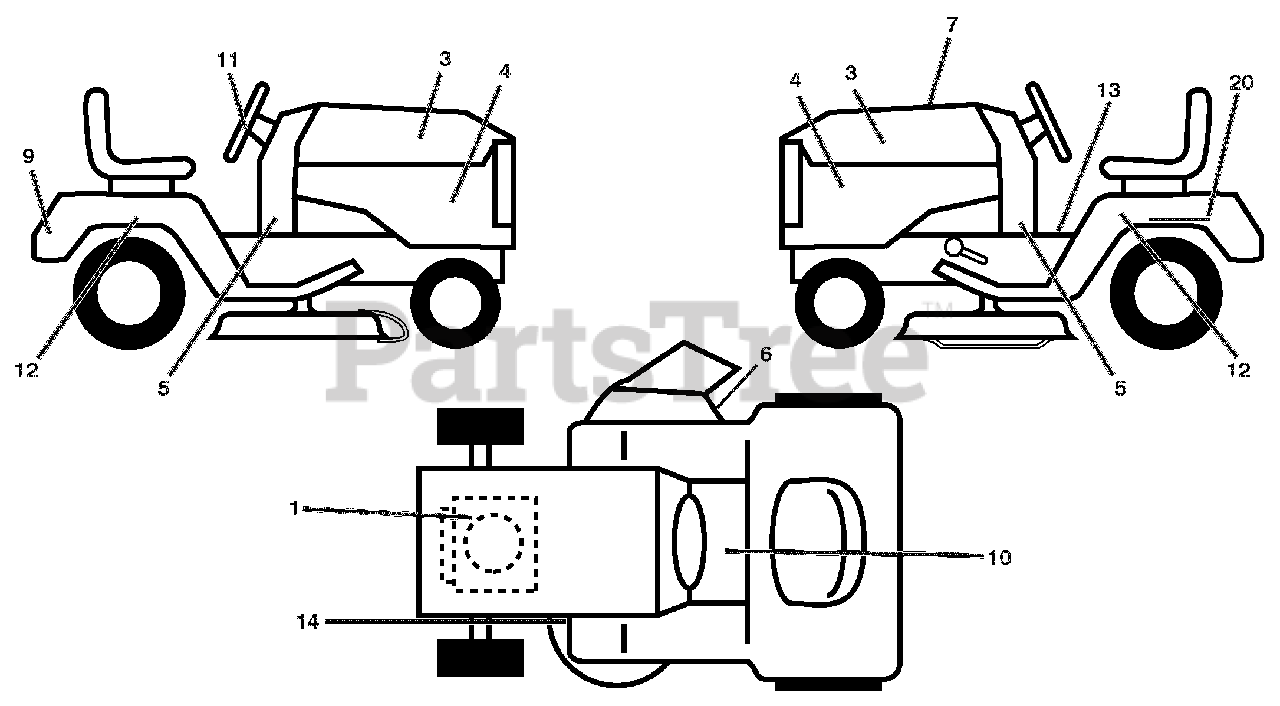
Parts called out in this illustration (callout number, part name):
1	DECAL ENGINE H.P.
3	DECAL.HOOD.LH/RH.
4	DECAL.SDPNL.PWRDBY B&S.ARIENS
5	DECAL.DASH.LWOWER.20HP.ARIENS
6	DECAL.MOWER.WARN.KEEP HAND AWY
7	DECAL.REPLACEMENT
9	DECAL.FENDER.REAR.ARIENS
10	DECAL, WARNING START INST.
11	DECAL.WHEEL.STEER.ARIENS
12	DECAL.FENDER.SIDE.HYDRO.ARIENS
13	DECAL.FENDER
14	DECAL.V-BELT.SCH.42/46"MEC/ELE
20	DECAL.BAT.DAN/POI P/L SYM.WPN
